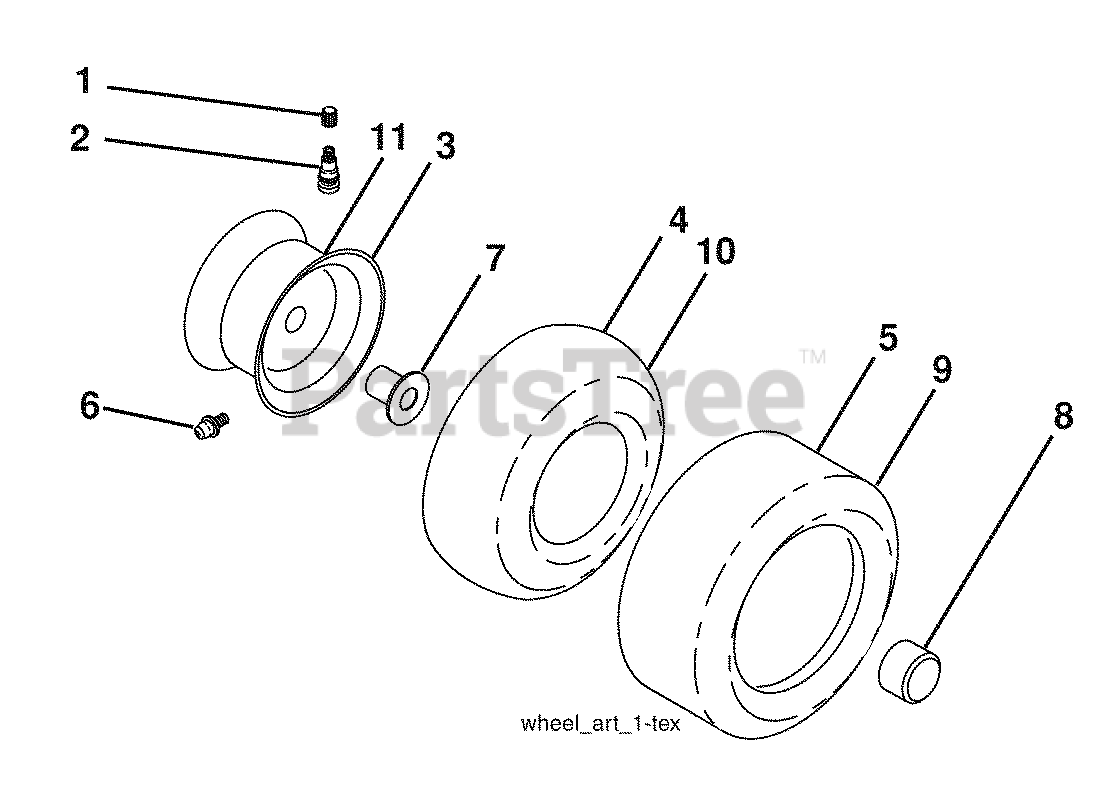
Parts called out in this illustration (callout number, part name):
1	Cap Valve Tire
2	Stem Valve
3	Rim Front
4	Tube Front
5	Tire Front 15 x 6.0-6
6	Fitting Grease
7	Bearing Flange
8	Cap Axle Blk 1 50 x 1 00
9	Tire R 18 x 9.5-8 Turf Saver LT
10	Tube Rear
11	Rim Asm 8" Rear
